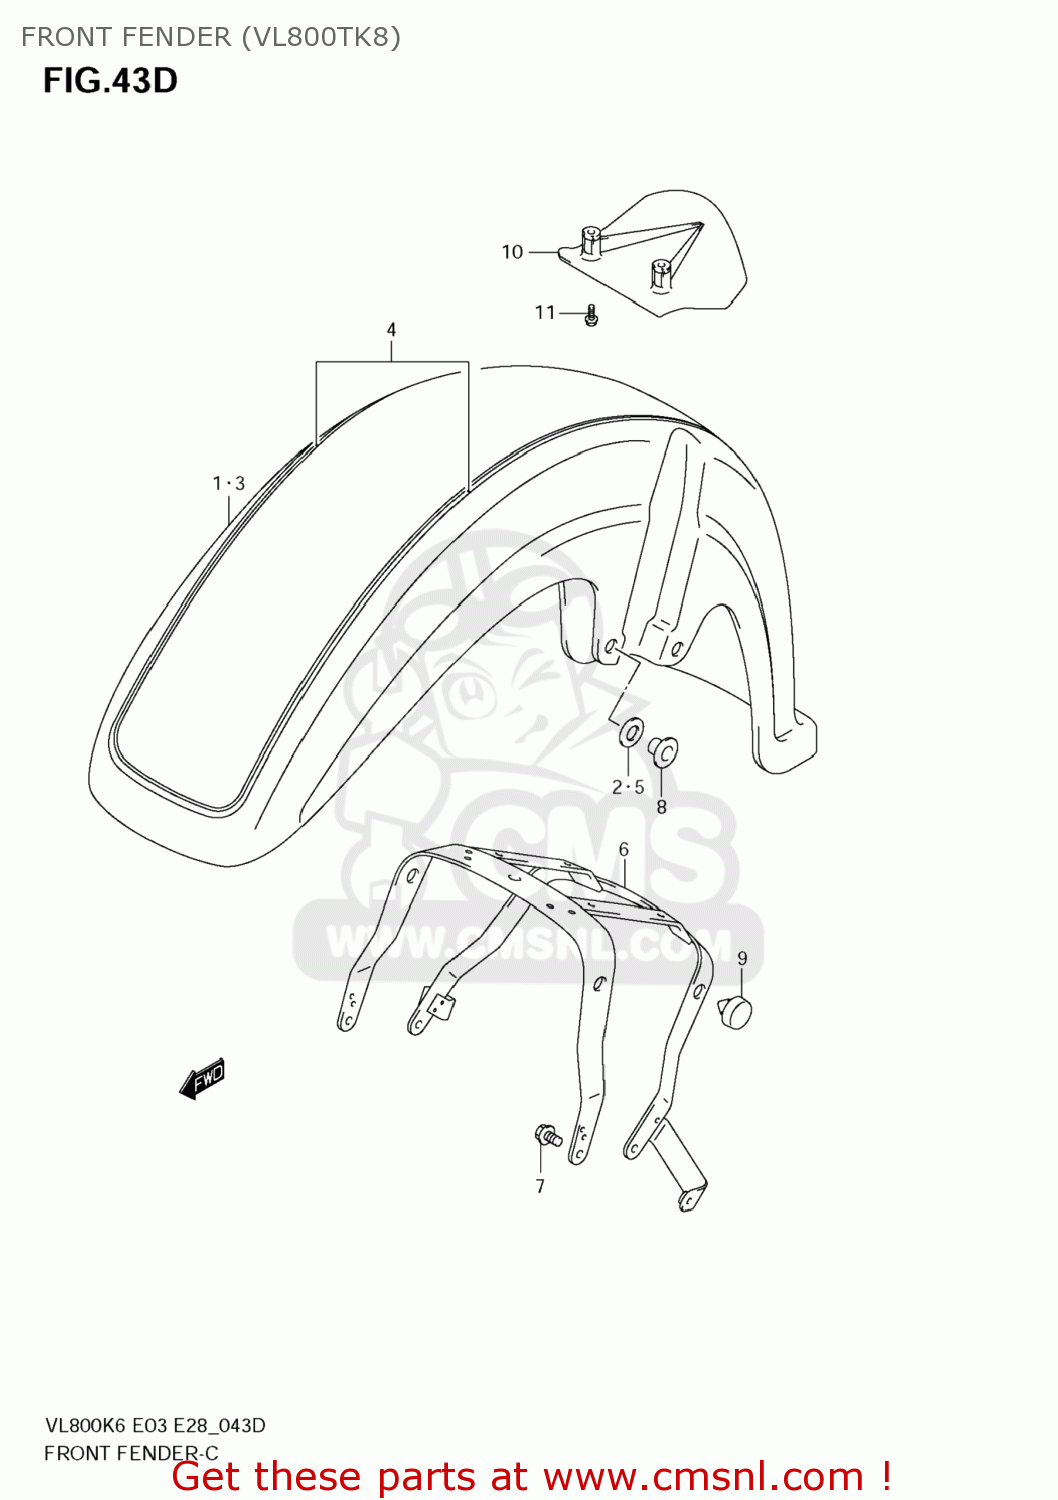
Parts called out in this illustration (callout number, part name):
1	FENDER,FR
2	CUSHION,FR FENDER
3	FENDER,FR
4	TAPE SET,FR FENDER
5	CUSHION,FR FENDER
6	BRACE,FR FENDER
7	BOLT
8	WASHER,FR FENDER
9	CUSHION
10	WING,FR
11	BOLT(6X16)
